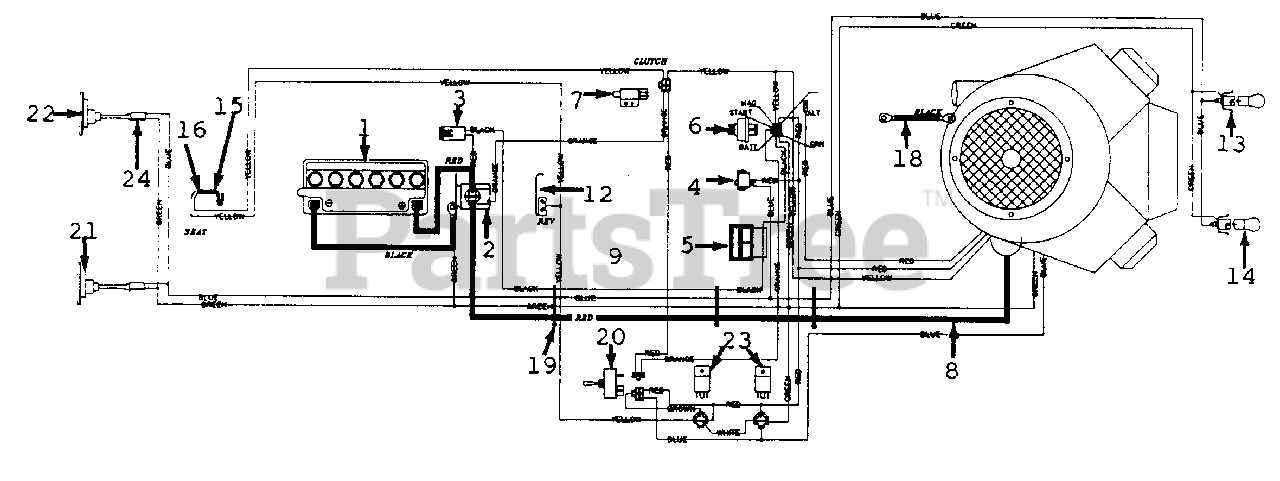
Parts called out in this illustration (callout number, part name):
1	Battery
2	Solenoid
3	Fuse 7.5 Amp.
4	Light Switch
5	Ammeter
6	Ignition Switch
7	Safety Switch
8	Electric Wire 30" Lg.
9	Wire Hamess
12	Safety Switch
13	Socket
14	Bulb
15	Safety Switch
16	Safety Switch
18	Ground Wire - 7.5" Lg.
19	Cable Tie
20	PTO Switch
21	Taillight Ass'y.
22	Taillight Bulb
23	Relay
24	Taillight Harness
